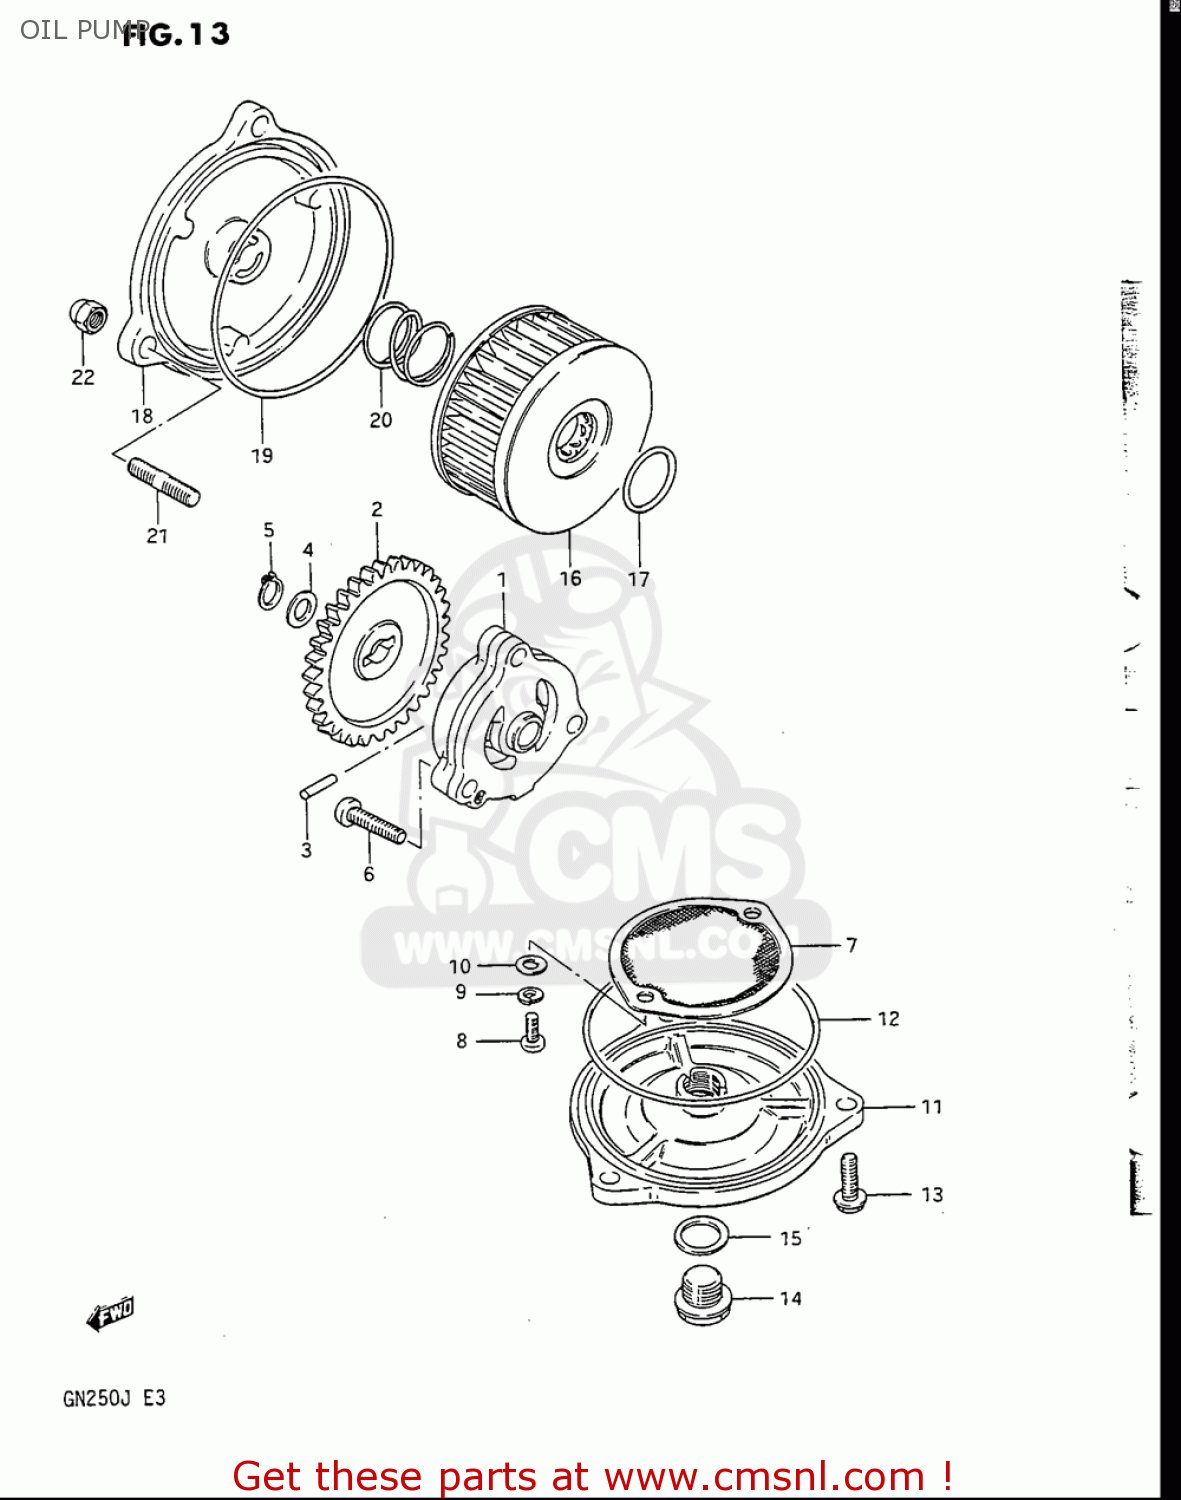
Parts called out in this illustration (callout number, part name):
1	PUMP ASSY,ENGINE OIL
2	GEAR,OIL PUMP DRIVEN(NT:33)
3	PIN(4X15.8)
4	SHIM
5	CIRCLIP
6	SCREW
7	STRAINER,ENGINE OIL
8	SCREW
9	LOCK,WASHER
10	WASHER
11	CAP,OIL STRAINER
12	O RING(D:2.4,ID:85)
13	BOLT
14	PLUG(MAGNETO)
15	GASKET(14X19.2X2) (NAS)
16	FILTER ASSY,ENGINE OIL
17	O RING(D:2.4,ID:15.8)
18	CAP,OIL FILTER
19	O RING(D:2.4,ID:73)
20	SPRING
21	BOLT,STUD
22	NUT
